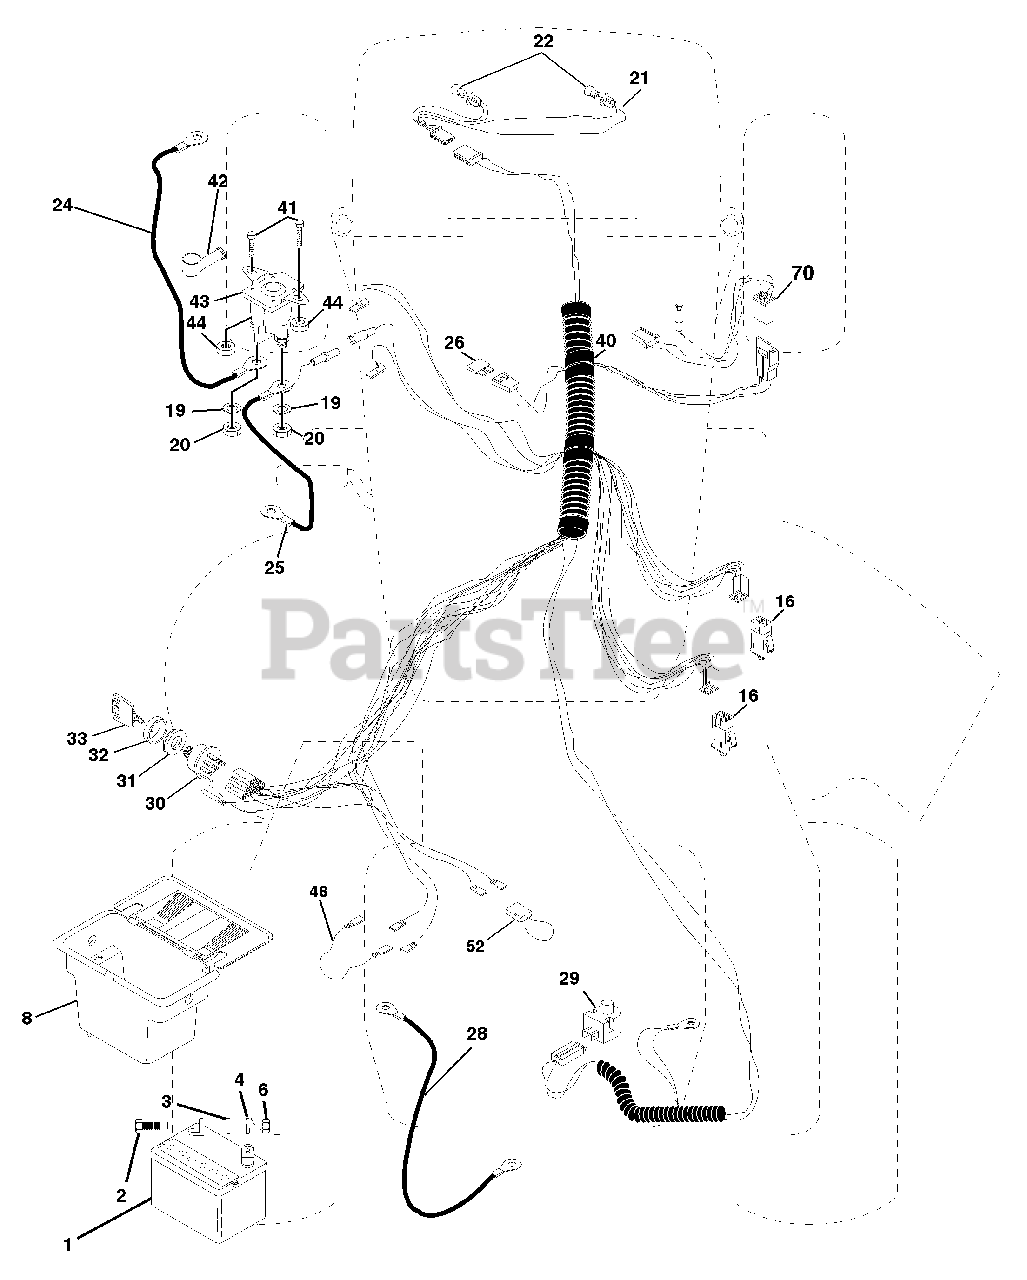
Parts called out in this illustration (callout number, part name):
1	Battery 12 Volt 25 Amp
2	Bolt Hex Hd 1/4-20unc X 3/4
3	Washer 9/32 X 5/8 X 16 Ga
4	Washer Lock Hvy Helical 1/4
6	Nut Fin Hex 1/4-20 Unc
8	Case Battery Mech Hinge
16	Switch Interlock Push-In
19	Washer Lock 1/4
20	Nut Jam Hex 1/4-20 Unc
21	Harness Asm Light W/4152j
22	Bulb Light #1156
24	Cable Battery 6 Ga 11" red
25	Cable Battery
26	Fuse 30 AMP Auto Green
28	Cable Ground 6 Ga 12" black
29	Switch Plunger Nc Gray
30	Switch Ign 4
31	Nut Ignition
32	Cover Sw Ignition
40	Harness Ign
41	Bolt Blk Fin Hex 1/4-20
42	Cover Terminal Red
43	Solenoid
44	Nut Keps Blk Hex 1/4-20 Unc
48	Adapter Ammeter
52	Protection Wire Loop
70	Harness Eng Briggs/Tec Dual
